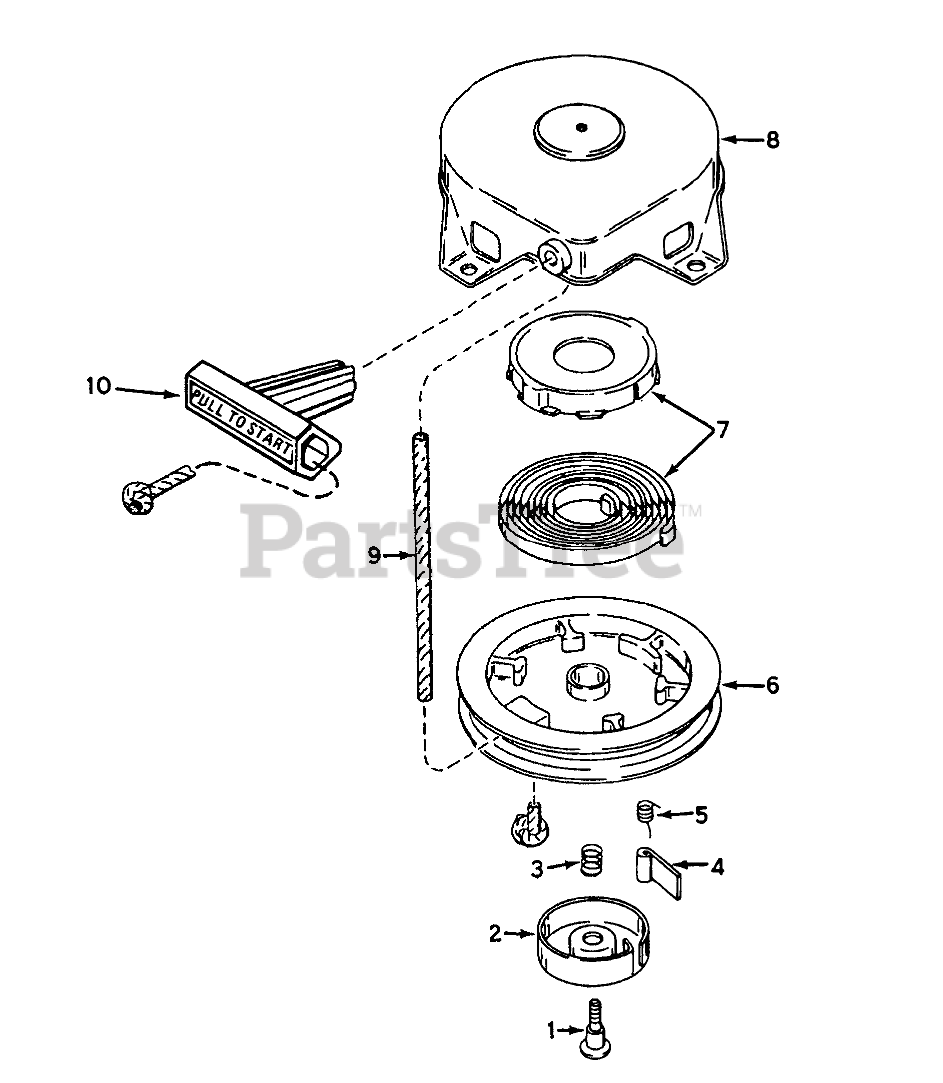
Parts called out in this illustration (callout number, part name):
2	Retainer
3	Spring-Brake
4	Dog-Starter
5	Spring-Dog
7	Spring & Keeper Assy
8	Housing-Starter
9	Rope-Starter (98 cut to length)
10	Handle-Starter
